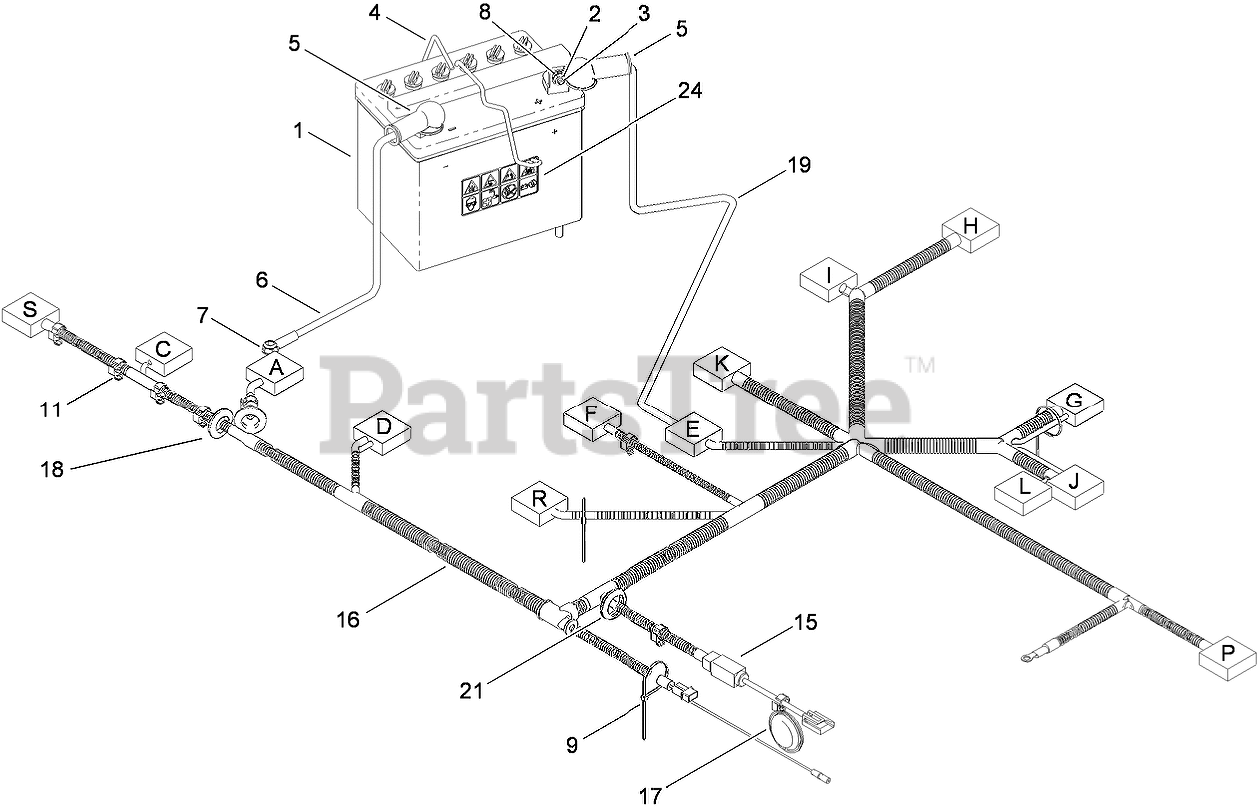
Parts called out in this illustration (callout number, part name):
1	BATTERY
2	NUT-HEX
3	SCREW-HH
4	CLAMP-BATTERY
5	BOOT-RUBBER
6	CABLE-BATTERY, NEGATIVE
7	NUT-LOCK, NI
8	WASHER-FLAT
9	TIE-CABLE
11	CLIP-SNAP
15	HARNESS-CLUTCH
16	HARNESS-WIRING
18	BUSHING
19	CABLE-BATTERY, POSITIVE
21	BUSHING
24	DECAL-DANGER
